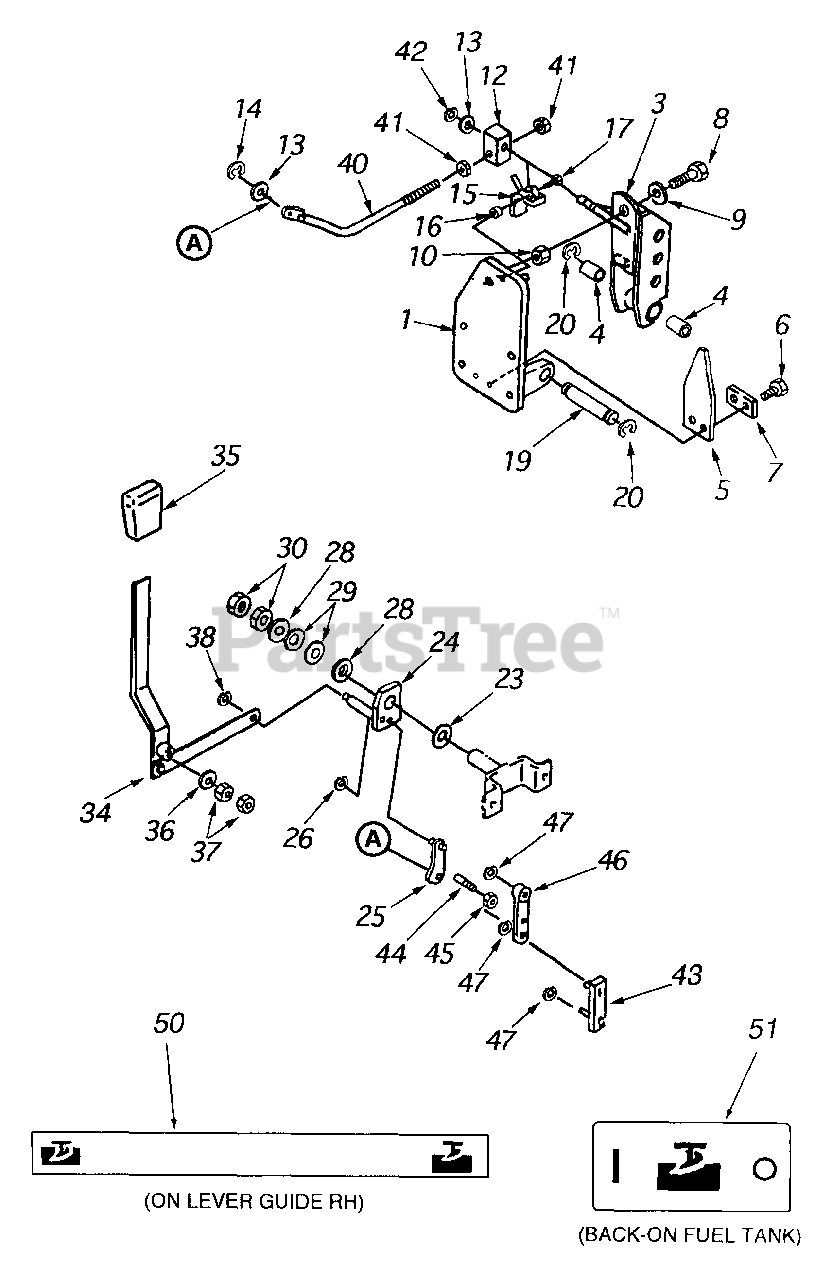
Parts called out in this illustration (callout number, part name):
3	Bracket, Top Link
34	Lever, D/C Ass'y.
46	Arm, Select
51	Label D, Lock
